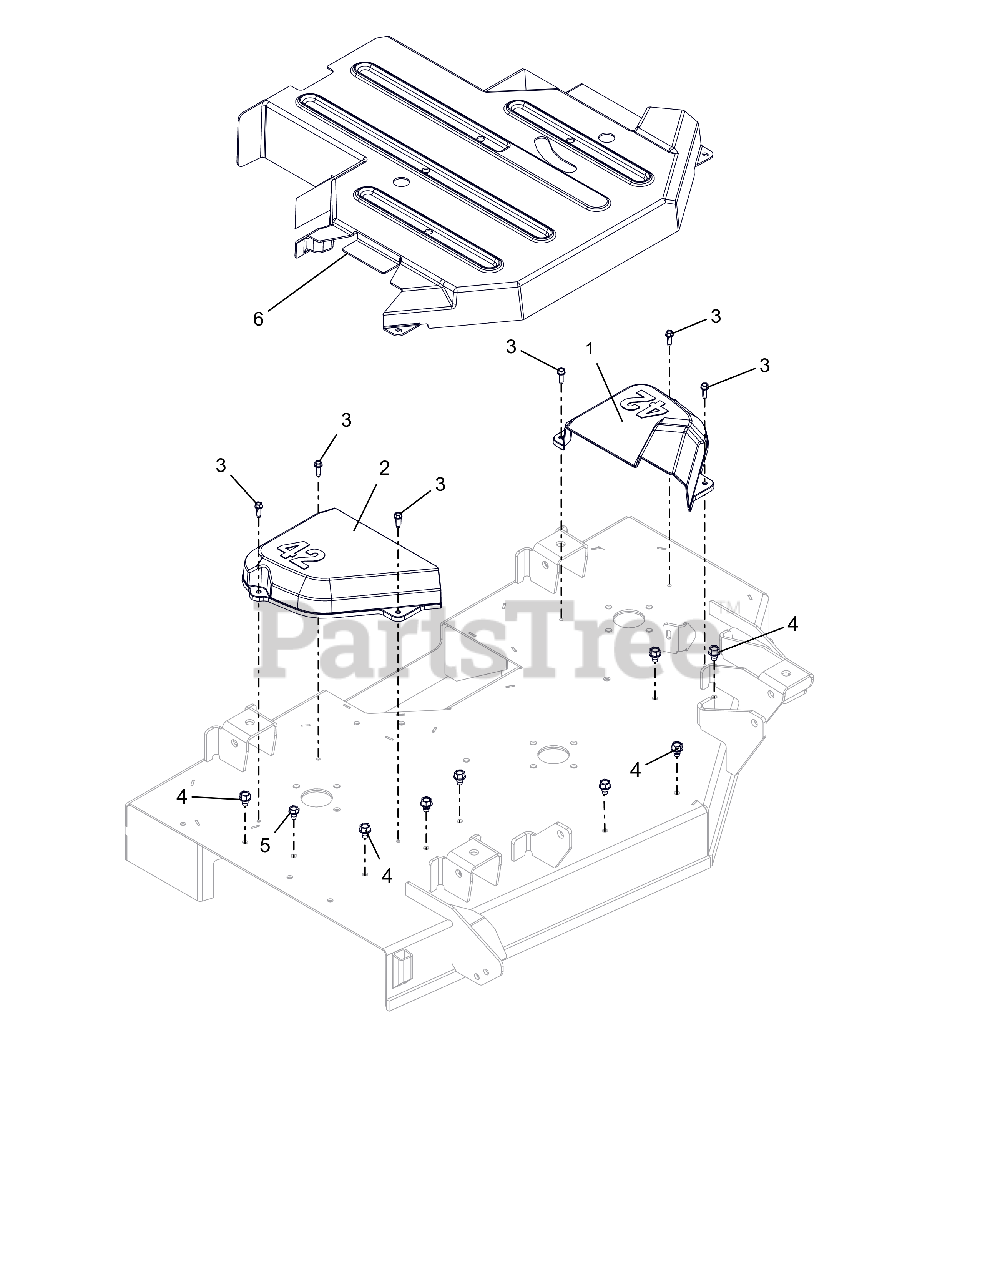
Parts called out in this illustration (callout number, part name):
1	COVER, BELT 42" LH
2	COVER, BELT 42" RH
3	SCR,TAP .25-20X.75 HWH TR ZCC
4	SCR,TAP .375-16X.50 HWH TR ZCC
5	SCR,TAP .312-18X.50 HWH TR ZCC
6	GUARD, IKON BELT-42" CE
